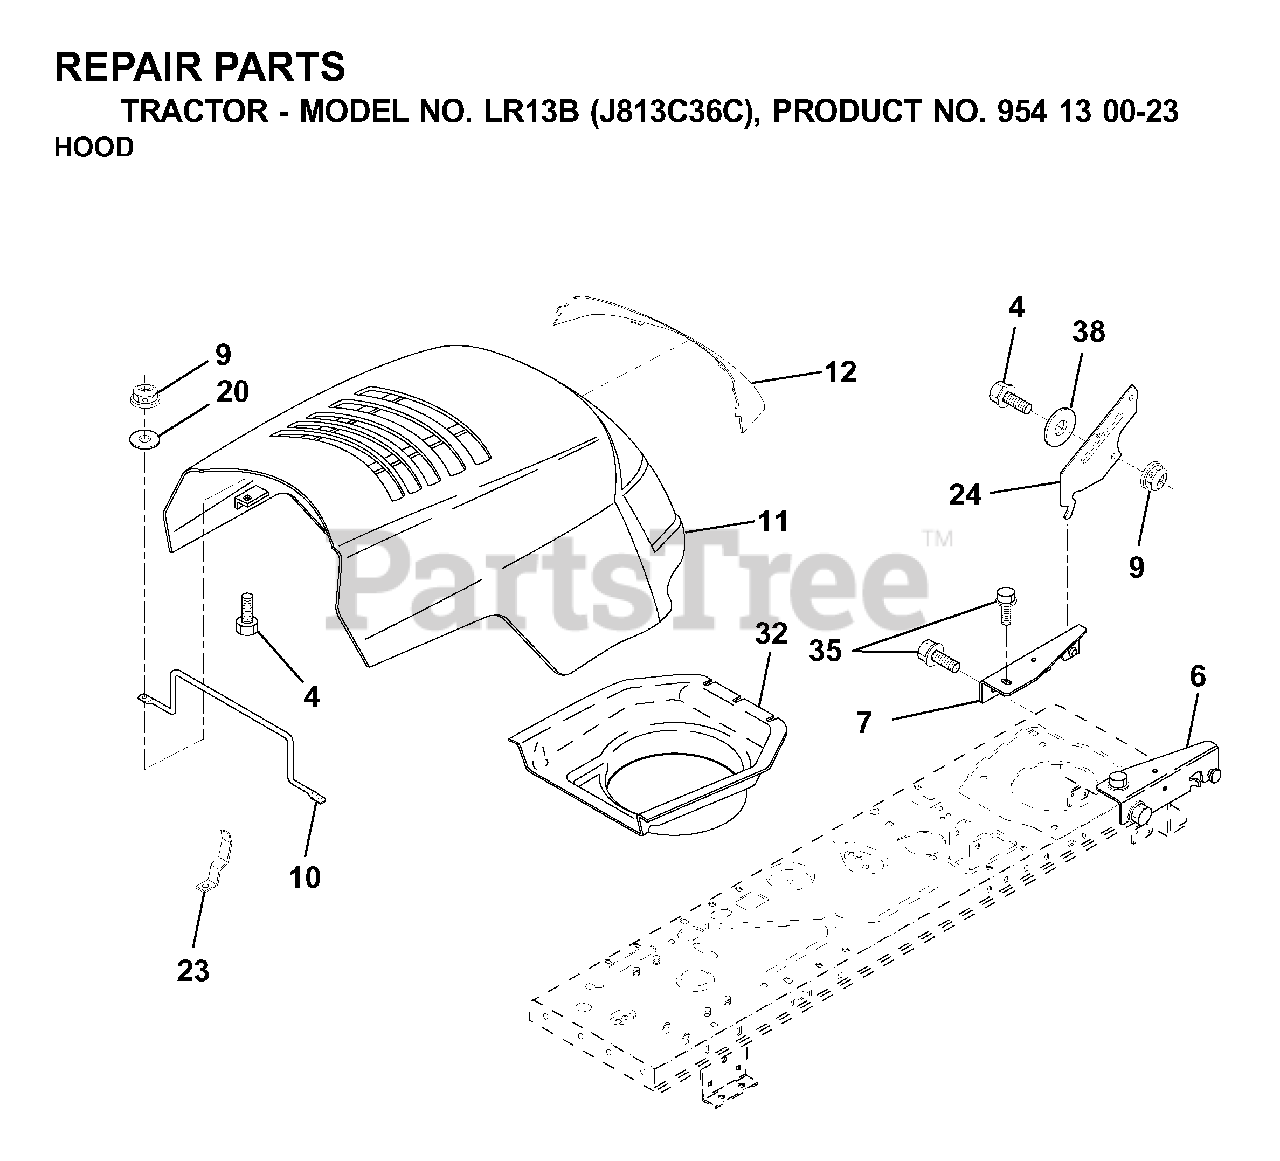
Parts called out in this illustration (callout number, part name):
6	BRACKET ASSY HOOD
7	BRACKET ASSY
9	LOCKNUT
20	WASHER
23	HOOD LATCH
35	SCREW
